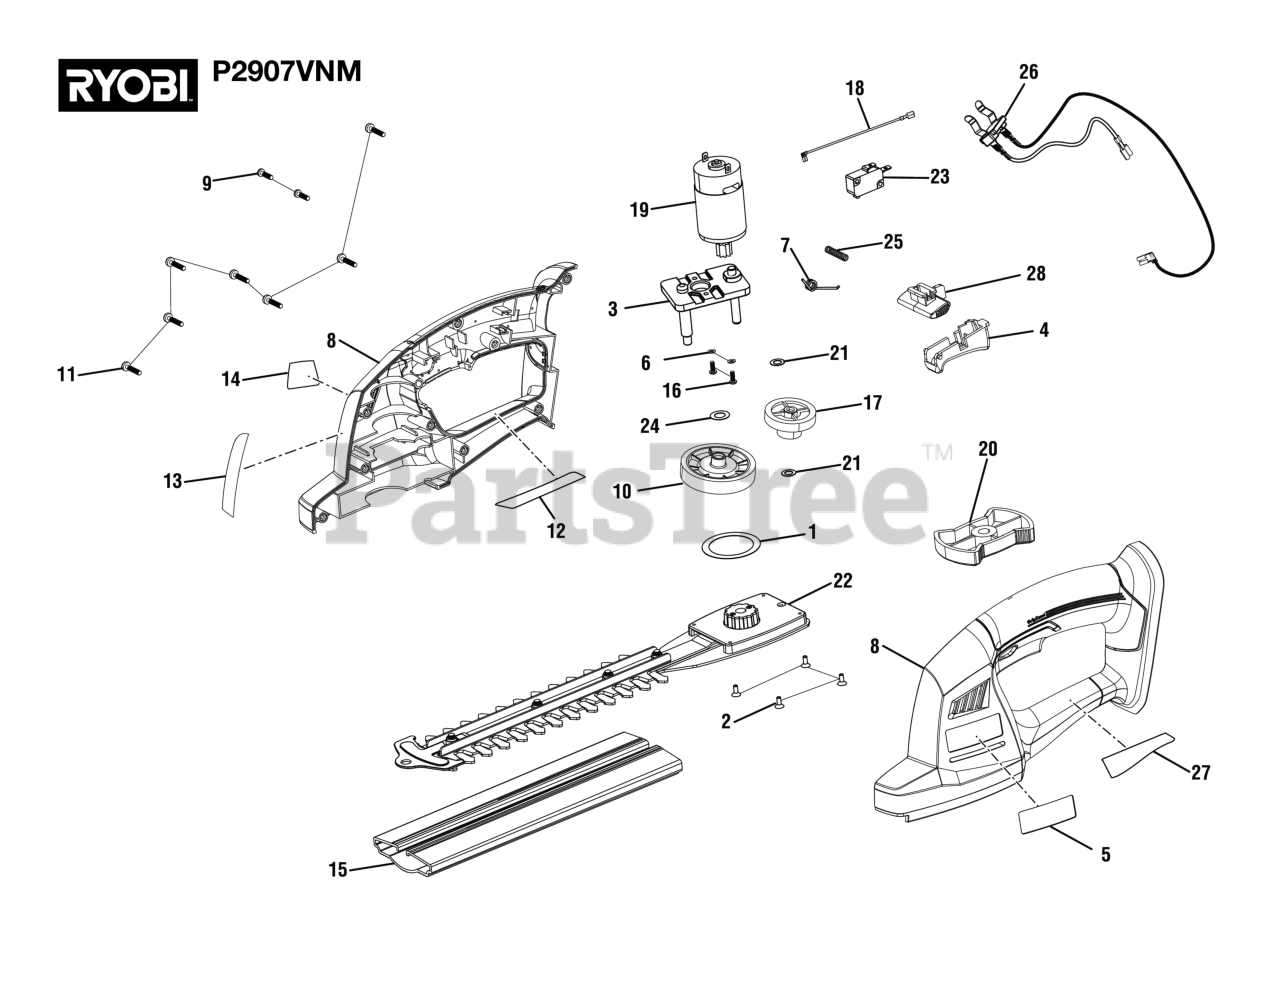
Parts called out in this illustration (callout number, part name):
2	Screw (M3 x 8.5 mm, Flat Hd.)
3	Motor Mount Assembly
5	Logo Label
6	Washer (OD5.7 x ID3.1 x 0.8t)
7	Trigger Spring
8	Housing Assembly
9	Screw (M3.5 x 12 mm, Pan Hd.)
11	Screw, M36.5x16mm, Pan. Head, Steel
12	Warning Label (Right, P2900VNM)
13	Icon Label
14	Data Label
16	Screw, M3x8mm, Steel
17	Step Gear
18	Receptacle and Wire Assembly
19	Motor and Pinion Assembly
20	Knob Assembly
21	Washer (M6, ID6.2 x 11OD x 0.3t)
22	Hedge Trimmer Blade Assembly
23	On/Off Switch
24	Washer, OD15xID8.4xT0.3
25	Compression Spring
26	Contact Plate Holder Assembly
27	Danger Label (Left, P2900VNM)
28	Lock-Off Button
